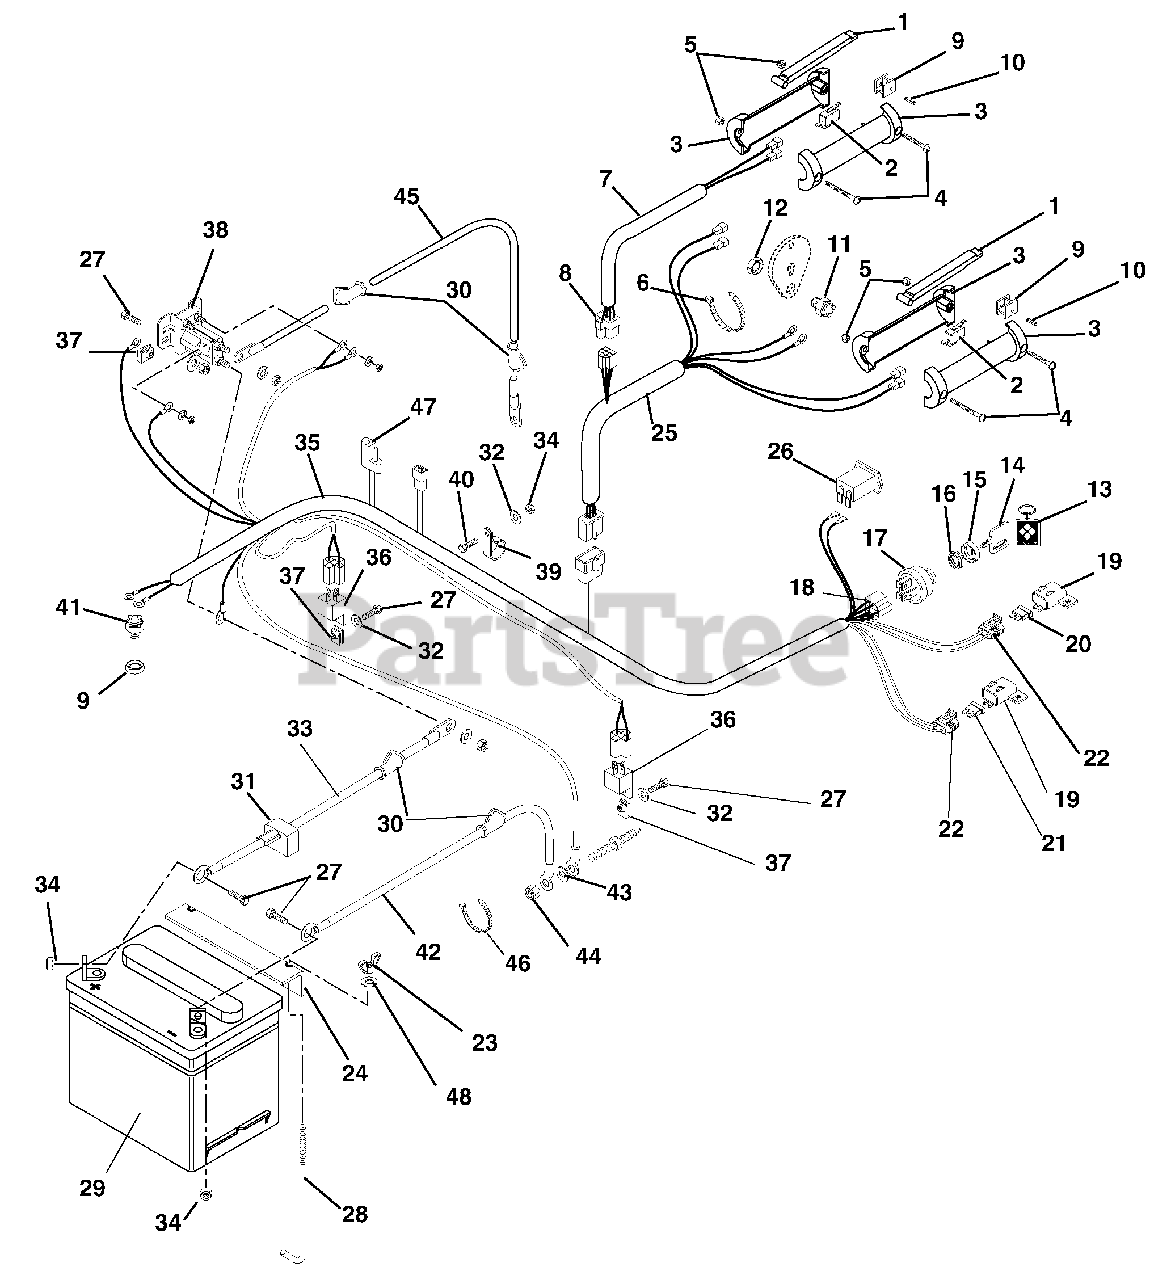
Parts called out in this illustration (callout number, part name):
1	Lever
2	Switch
3	Handle-Left Hand & Right Hand
4	Screw-Machine 10-24 x 1.50
5	Nut-Locking-Nylon 10-24
6	Tie Wrap-Black
7	Harness-Steering Brake (114,117, 119, 309)
8	Connector
9	Holder-Switch
10	Pin-Roll .094 x .750
11	Switch-Interlock Closed (Forward/Reverse)
12	Nut-Stamped .56-18
13	Key Chain
14	Key Switch
15	Cap-Ignition Switch
16	Nut-Panel .562-24
17	Ignition Switch (115, 117, 119, 307, 309, 311-313)
17	Ignition Switch (114)
18	Connector
19	Cover (114, 115, 117, 307, 309, 311-313)
19	Cover (119)
20	Fuse-30 AMP (115,117, 307, 309, 311, 312)
20	Fuse-20 AMP (119)
20	Fuse-25 AMP (114)
21	Fuse-15 AMP (119)
22	Assembly-Connector Weather Tight (114, 115, 117, 307, 309, 311-313)
22	Assembly-Connector Weather Tight (119)
23	Nut-Wing .250-20
24	Hold Down
25	Harness-Wiring Handlebar (114)
25	Harness-Wiring Handlebar (115,117,119, 307, 309, 311, 312)
26	Hour Meter
27	Screw-Machine 10-24 x .75 Hex Washer Head (114, 115, 117, 307, 309, 311-313)
27	Screw-Machine 10-24 x .75 Hex Washer Head (119)
28	Tie Down
30	Boot-Insulator
31	Insulator
32	Washer-Flat-Steel .281 x .620 x .065
33	Cable-Battery to Solenoid (115, 117, 119, 307, 309, 311, 312)
33	Cable-Battery to Solenoid (114)
34	Nut-Locking-Center .25-20
35	Harness-Wiring (114)
35	Harness-Wiring (115, 117, 307, 309, 311, 312)
35	Harness-Wiring 12 HP Kohler (119)
36	Relay (115, 117, 307, 309, 311, 312)
36	Relay (119)
37	Nut-Retaining Ring #10-24
38	Solenoid
39	Clamp-Cushioned Steel
40	Bolt-Hex .25-20 x .75 Grade 5
41	Switch-Interlock Open (PTO)
42	Cable-Negative Battery
43	Washer-Flat-Steel .406 x .812 x .065
44	Nut-Locking-Center .375-16 Grade 2
45	Cable-Solenoid to Starter (115, 117, 119, 307, 309, 311, 312)
45	Cable-Solenoid to Ground (114)
46	Tie Wrap Black
47	Molded Diode Plug- Clear 1 AMP
48	Washer-Flat-Steel .312 x.734 x .065
